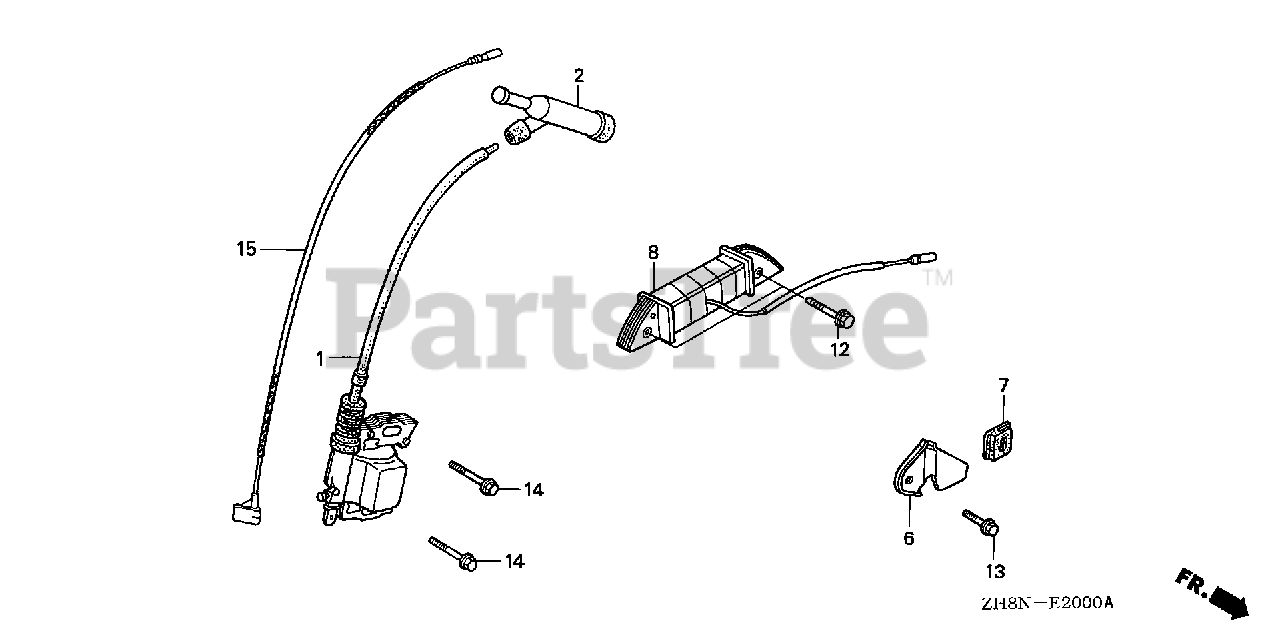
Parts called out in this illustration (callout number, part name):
1	COIL ASSY., IGNITION
2	CAP ASSY., NOISE SUPPRESSOR
14	BOLT, FLANGE (6X25)
15	WIRE, STOP SWITCH (370MM)
